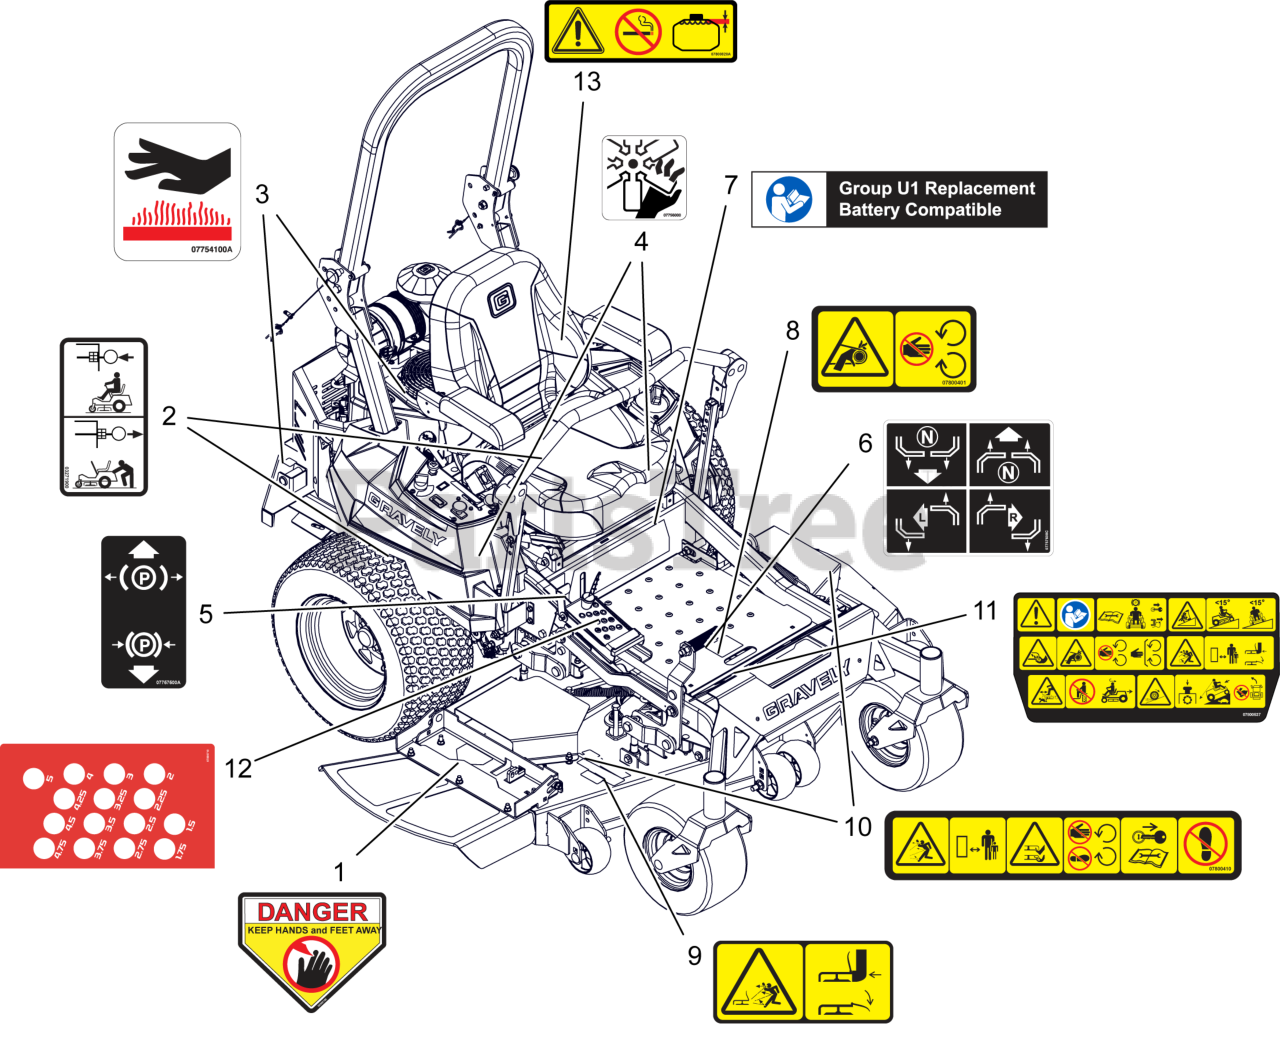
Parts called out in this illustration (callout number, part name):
1	DECAL, DANGER
2	DECAL, TRANSMISSION DISCONNECT
3	DECAL, HOT SURFACE
4	DECAL, DANGER FAN
5	DECAL, PARKING BRAKE LEVER
6	DECAL, INSTRUCTIONAL-STEERING
7	DECAL, U1 BATTERY REPLACEMENT
8	DECAL, SAFETY - GUARDING
9	DECAL, SAFETY - DECK GUARDING
10	DECAL, DECK SAFETY
11	DECAL, MAIN SAFETY
12	DECAL - HOC
13	DECAL, FUEL WARNING
